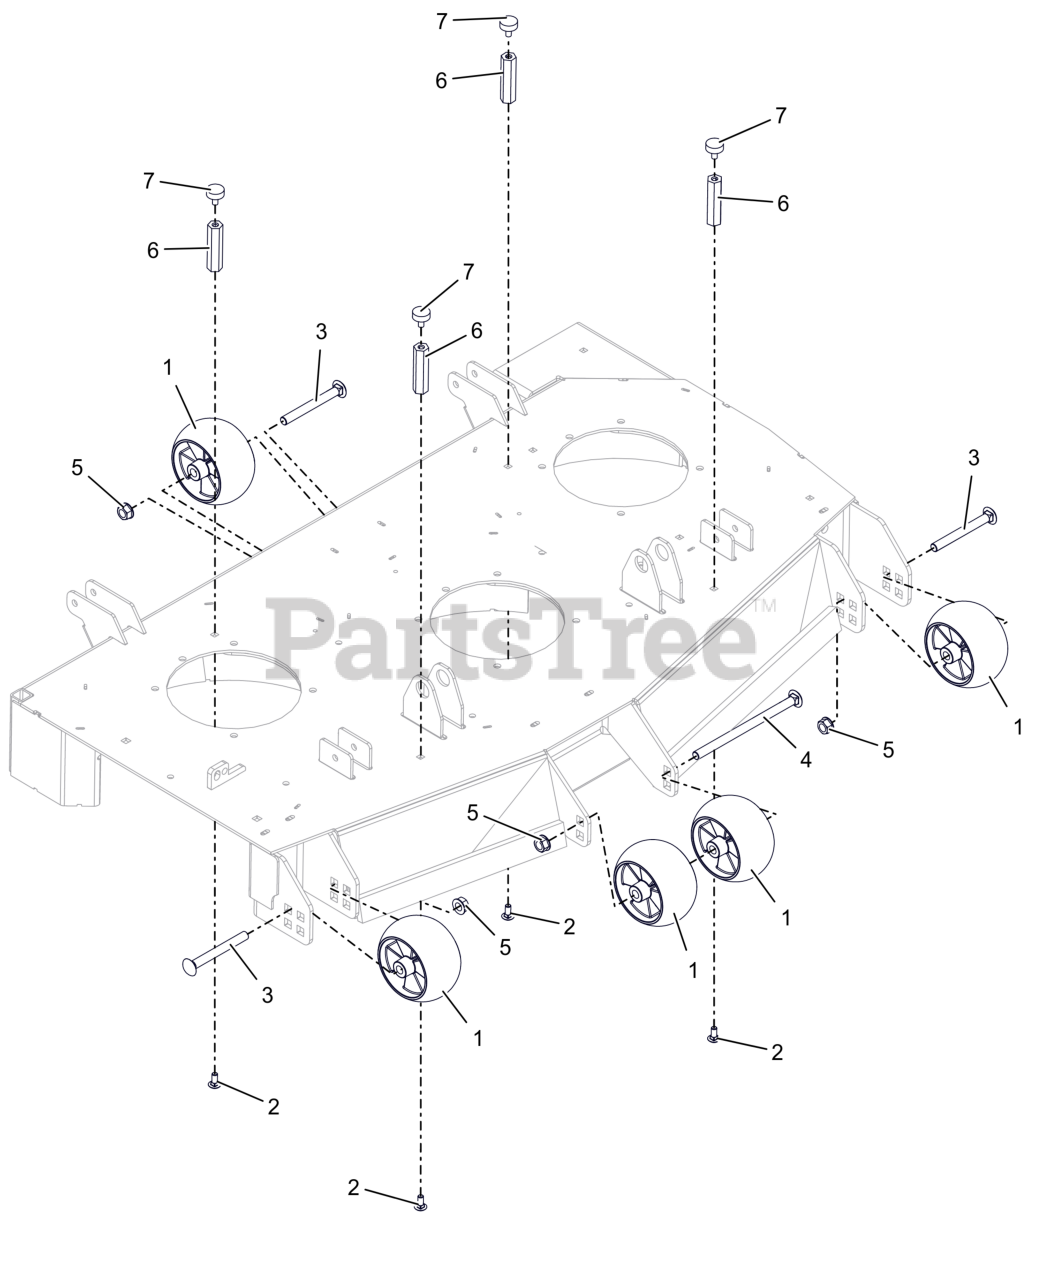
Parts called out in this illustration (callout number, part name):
1	WHEEL, ANTI SCALP - 5X3 CTR W/RIBS
2	BLT, RHSN .31-18X.75 G5 ZCC LT
3	BLT-RHNS .50-13X4.50 G5 ZCC NS
4	BLT-RHSN .50-13X8.00 G5 ZCC NS
5	NUT-LK-CTR-FLG .500-13 GG ZCC
6	NUT, COUPLING .31-18 X 3.00
7	BUMPER, RUBBER
